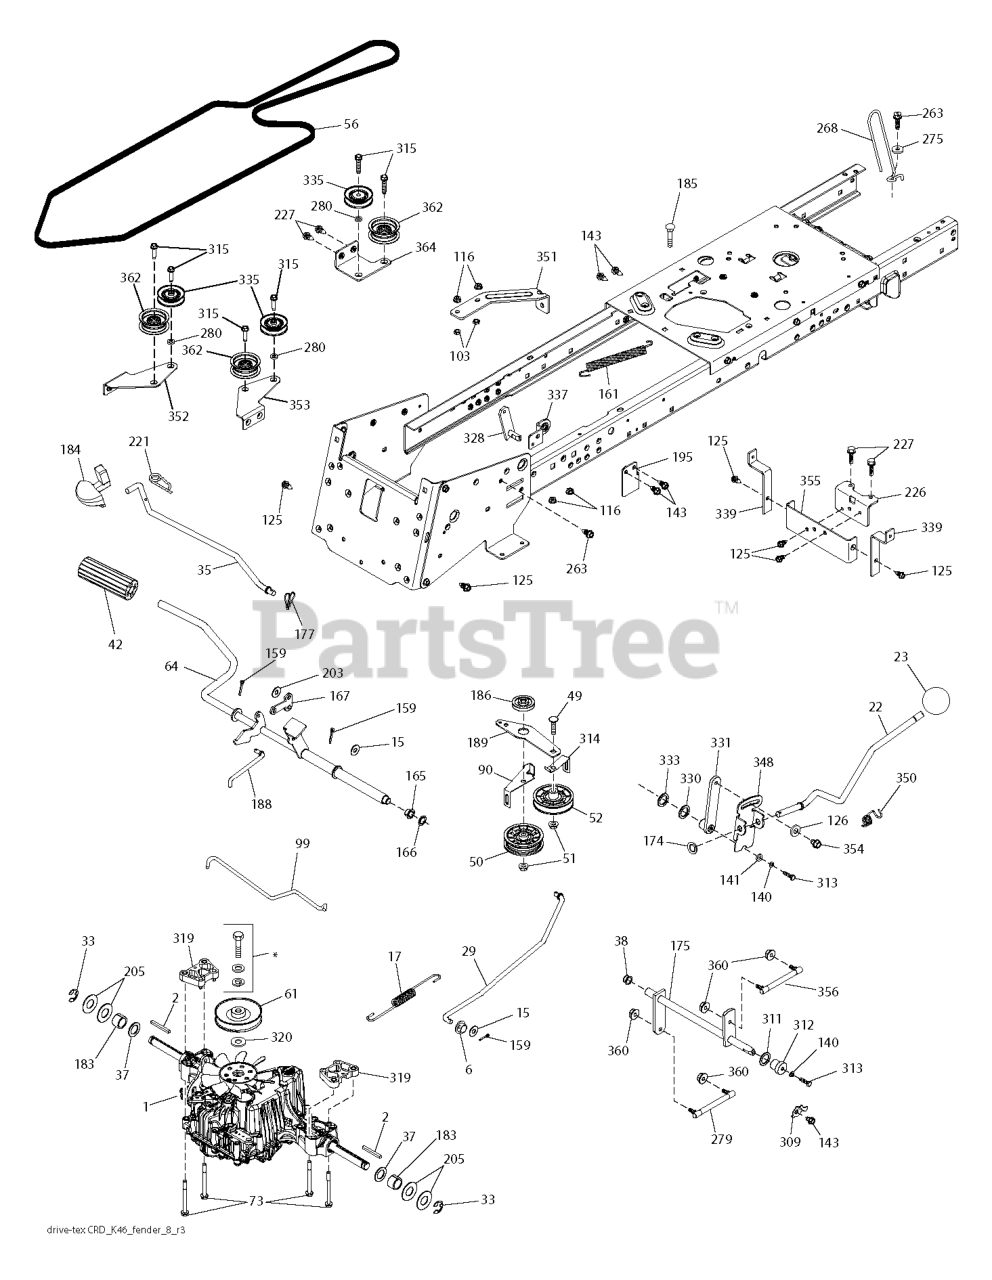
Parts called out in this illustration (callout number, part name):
1	TRANS.K46DC.CRD.FS.7A646084421
2	SQUARE KEY
6	BUSHING.SNAP.NYL.BLK.
15	WASHER PLAIN WASHER 3/8 X 0.08
17	SPRING
22	ROD ROD SHIFT FENDER
23	KNOB.DELUXE.(PISTOL.GRIP).BLAC
29	ROD
37	WASHER.HARDENED
38	NYLINER SNAP 5/8" ID
42	PEDAL COVER
50	IDLER.FLAT.910.OFFSET
51	NUT LOCK FLG 3/8-16 UNC
52	IDLER.V-GROOVE.910.OFFSET
61	PULLEY
64	SHAFT.ASM.PEDAL.BRAKE.
73	BOLT.HEX.FLNG.5/16-18X3.75
90	KEEPER KEEPER BELT CLUTCHING T
99	ROD ROD BYPASS CRD TEX GEN 2
125	SCREW
140	WASHER SPRING LOCK WASHER WITH
161	SPRING, RETURN LT
165	BUSHING.SHAFT.BRAKE.HAND
166	NUT.PUSH.625
167	LATCH.BRAKE.SPRING
174	NUT.PUSH.500.2006
175	SHAFT SHAFT CROSS SHIFT REAR F
177	PIN COTTER;LOCKING;BOWTIE;1IN
183	SPACER AXLE
184	HANDLE.PARKNG BRK.PRED.LT.428
186	SPACER.RETAINER
188	LINK.CLUTCH.GROUND DRIVE.LONG
189	BELLCRANK BELLCRANK GROUNDDRI
195	BRACKET.ROD.BRAKE
203	WASHER 11/32 X 11/16 X 14 GA T
221	RETAINER.SPRING.CLIP.H
226	BRACKET.MOUNT.TORQUE.K46.TLT
263	SCREW, 3/8-16X3/4
309	PLATE FASTENING LT
311	WASHER NYL
312	HUB.TAPERED.ROUND.CRD
314	RETAINER KEEPER BELT
315	BOLT.5/16-18X1.25
319	SPACER SPACER TRANSAXLE TEX C
320	WASHER.SPACER.MANDREL
328	SHAFT SUBASM SHAFT CROSS FRONT
330	WASHER.NYL.7/8IDX.105"HYD CR
331	HUB HUB SHIFT FENDER
333	WASHER.WAVE.SPRING
335	PULLEY.V-IDLER.
337	BRACKET BRACKET SUPT SHIFT CR
339	STRAP STRAP TORQUE K46 CRD TE
348	ARM ARM CLEVIS ROD SHIFT TEX C
350	TORSION SPRING SPRING TORSION
351	BRACKET BRACKET DECK SWAY
352	BRACKET BRACKET.IDLER
353	BRACKET
355	STRAP STRAP TORQUE K46 CRD TEX
360	NUT NUT HEX CENTERLOCK 5/16-24
362	IDLER.FLAT.2.25.INCH
364	BRACKET BRACKET IDLER CRD TEX
